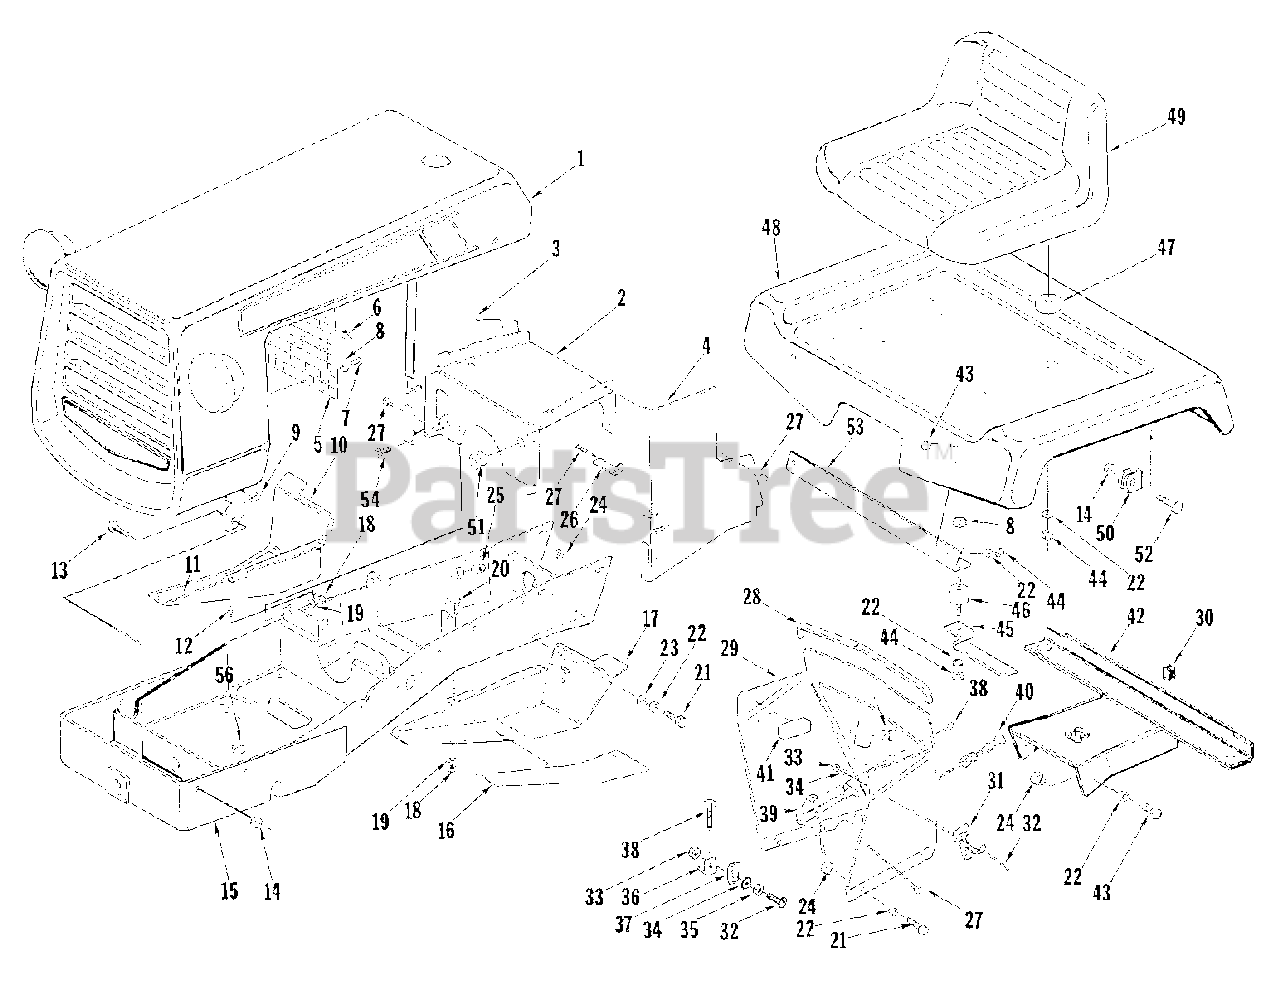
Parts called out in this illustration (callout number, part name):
1	HOOD ASSEMBLY
2	SUPPORT ASSEMBLY, Battery
3	PANEL, Side, R.H.
4	PANEL, Side, L.H.
5	SCREEN, Grille
10	FOOT REST, R.H.
11	PAD, Foot, R.H.
12	FITTING, Lube
13	BOLT, Carriage, 3/8-16 x 3/4
14	NUT, Hex Lock, 3/8-16
15	FRAME ASSEMBLY
16	PAD, Foot, L.H.
17	FOOT REST, L.H.
18	NUT, Hex Head, 3/8-16
19	WASHER, Lock, 3/8
20	SCREW, Hex Cap, 3/8-16 x 7/8
21	SCREW, Hex Head Cap, 5/16-18 x 3/4
22	WASHER, Lock, 5/16
23	WASHER, Flat
24	NUTSERT, Fastening
25	BEARING, Sleeve
26	CLIP, Closed
27	SCREW, Taptite, 1/4-20 x 1/2
28	MOULDING, Dash
29	PANEL ASSEMBLY, Instrument
32	SCREW, Round Head, 10-24 x 3/8
33	NUT, Hex, 10-24
34	WASHER, Lock, #10, Extension Tooth
36	BRACKET, Throttle Cable
37	CLIP, Throttle Cable
38	SCREW, Tapping, 1/4-20 x 5/8
40	CHOKE (Includes Nut & Washer)
41	GASKET, Felt
42	COVER ASSEMBLY, Frame
43	SCREW, Hex Head Cap, 5/16-18 x 5/8
44	NUT, Hex 5/16-18
45	CLIP, Spring
46	CONNECTOR, Cushion
47	CONNECTOR, Cushion
48	DECK ASSEMBLY, Seat
50	STOP, Seat Deck
51	GROMMET (T-10, T-12)
51	GROMMET (T-15)
52	SCREW, Hex Head Cap, 3/8-16 x 1-1/4
53	BRACE, Front Seat Deck
54	SCREW, Hex Cap, 3/8-16 x 3/4
55	WASHER, 5/16
